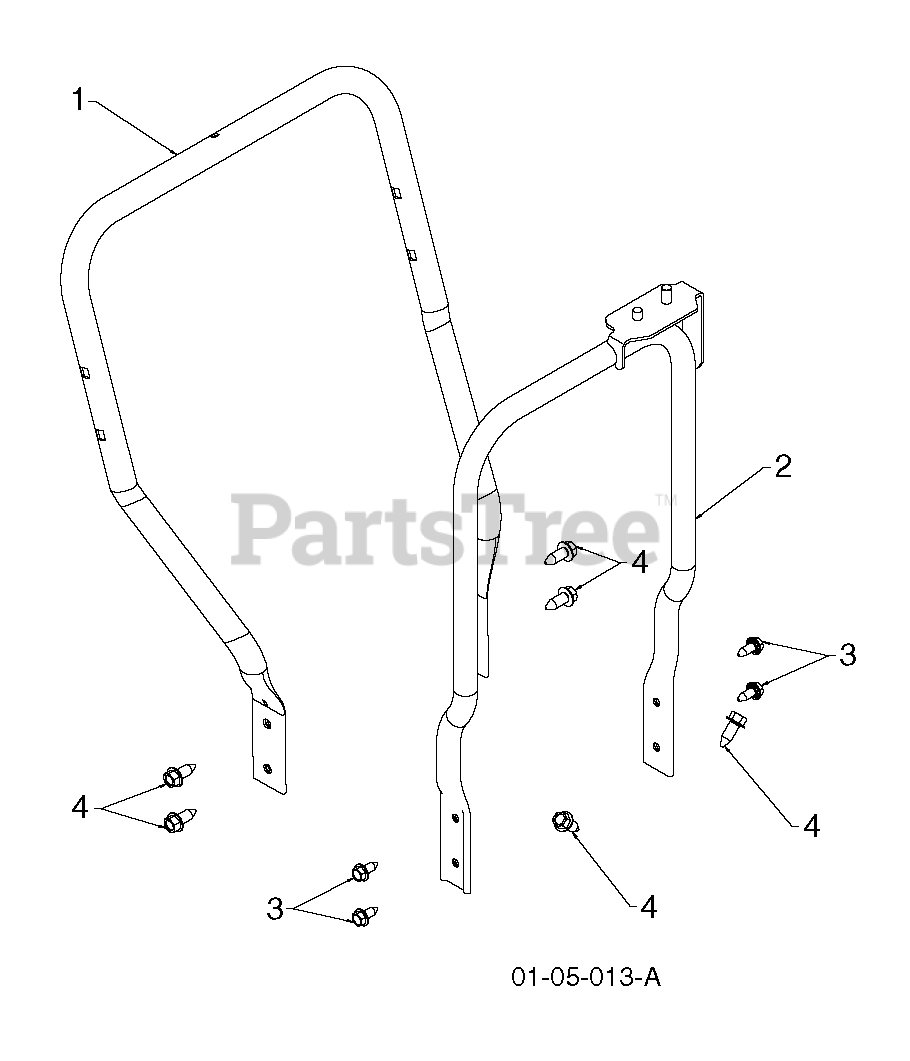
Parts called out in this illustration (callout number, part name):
1	TUBE.LOWER.PNT.BLACK
2	SUPPORT.WELDMENT.ROTATOR.BLACK
3	BOLT.HEX.HD.WASHER.5/16-18X.75
4	SCREW 3/8-16X1
